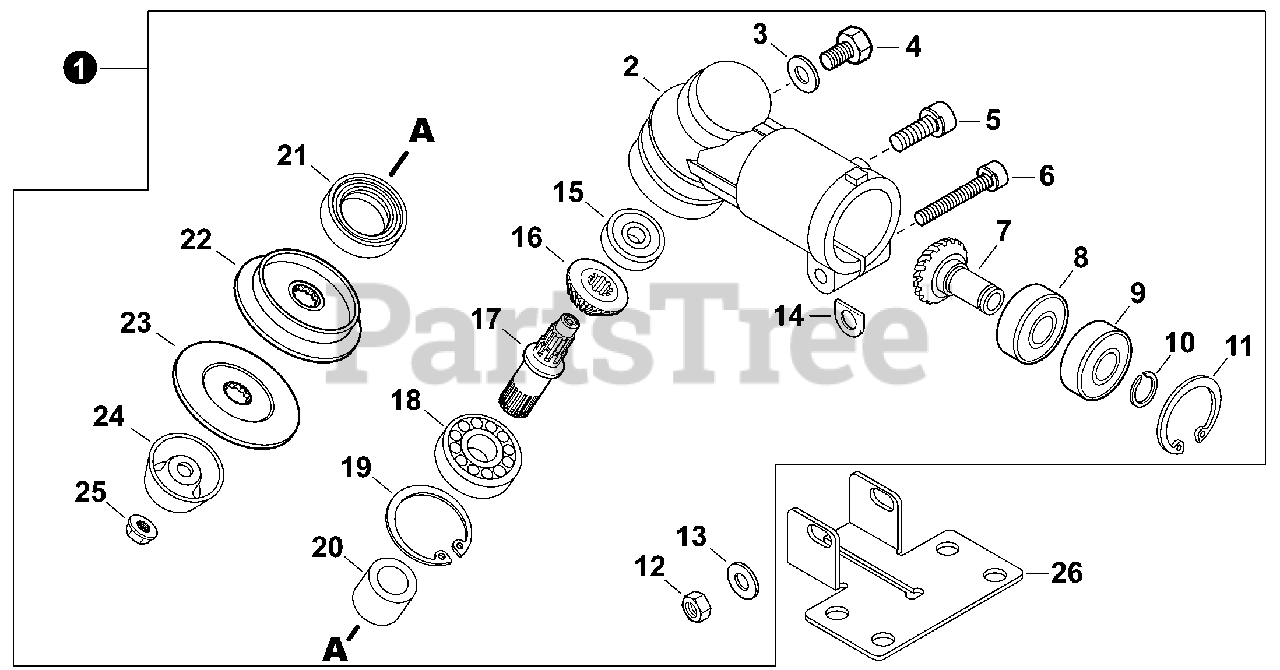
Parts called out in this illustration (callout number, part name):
1	GEAR CASE ASSY
2	HOUSING, GEAR CASE
4	BOLT M6x10
5	BOLT 5x16
6	BOLT M5x35
7	GEAR, PINION
8	BEARING, BALL 608
9	BEARING, BALL 608ZZ
10	E-RING 8
11	RING, SNAP 22
13	WASHER 5.5x12x0.8
14	D-WASHER
15	BEARING, BALL 626 DDU
16	GEAR, BEVEL
17	SHAFT, GEAR
18	BEARING, BALL 6001
19	RING, SNAP 28
20	COLLAR 10
21	SEAL, OIL
22	PLATE, ADAPTOR - UPPER
23	PLATE, ADAPTOR - LOWER
25	NUT, LOCK 10 - NYLON INSERT
26	PLATE, SHIELD MOUNTING
